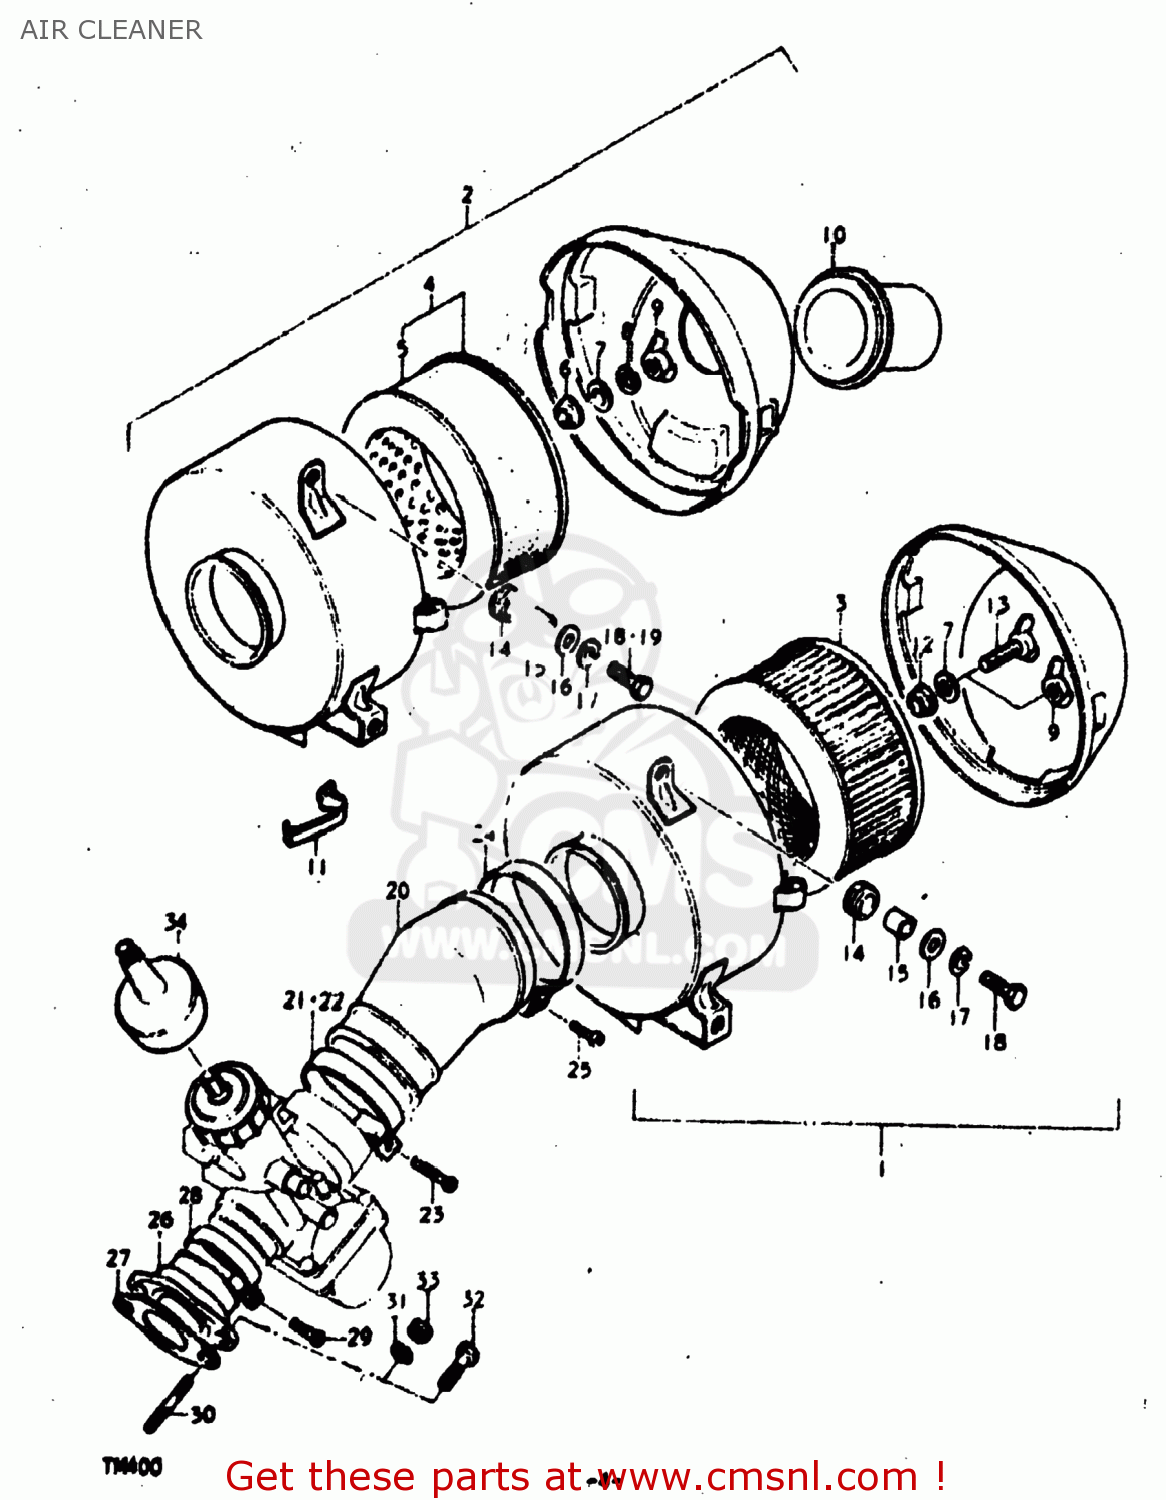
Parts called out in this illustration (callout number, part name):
1	CLEANER ASSEMBLY,AIR
2	CLEANER ASSEMBLY,AIR
3	FILTER,AIR CLEANER
4	FILTER,AIR CLEANER
5	ELEMENT,AIR CLEANER
7	WASHER
8	LOCK WASHER
9	NUT
10	PIPE, INLET
11	SPRING,AIR CLEANER
14	CUSHION
15	SPACER (7X9X7)
16	WASHER (6.5X20X1.2)
17	LOCK WASHER
18	BOLT
19	BOLT
20	TUBE,AIR CLEANER OUTLET
21	CLAMP
22	CLAMP
23	SCREW
24	CLAMP
25	SCREW
26	PIPE,INTAKE
27	GASKET,CARBURETOR (NAS)
28	CLAMP
29	SCREW
30	STUD BOLT
31	LOCK WASHER
32	BOLT
33	NUT
34	CAP
